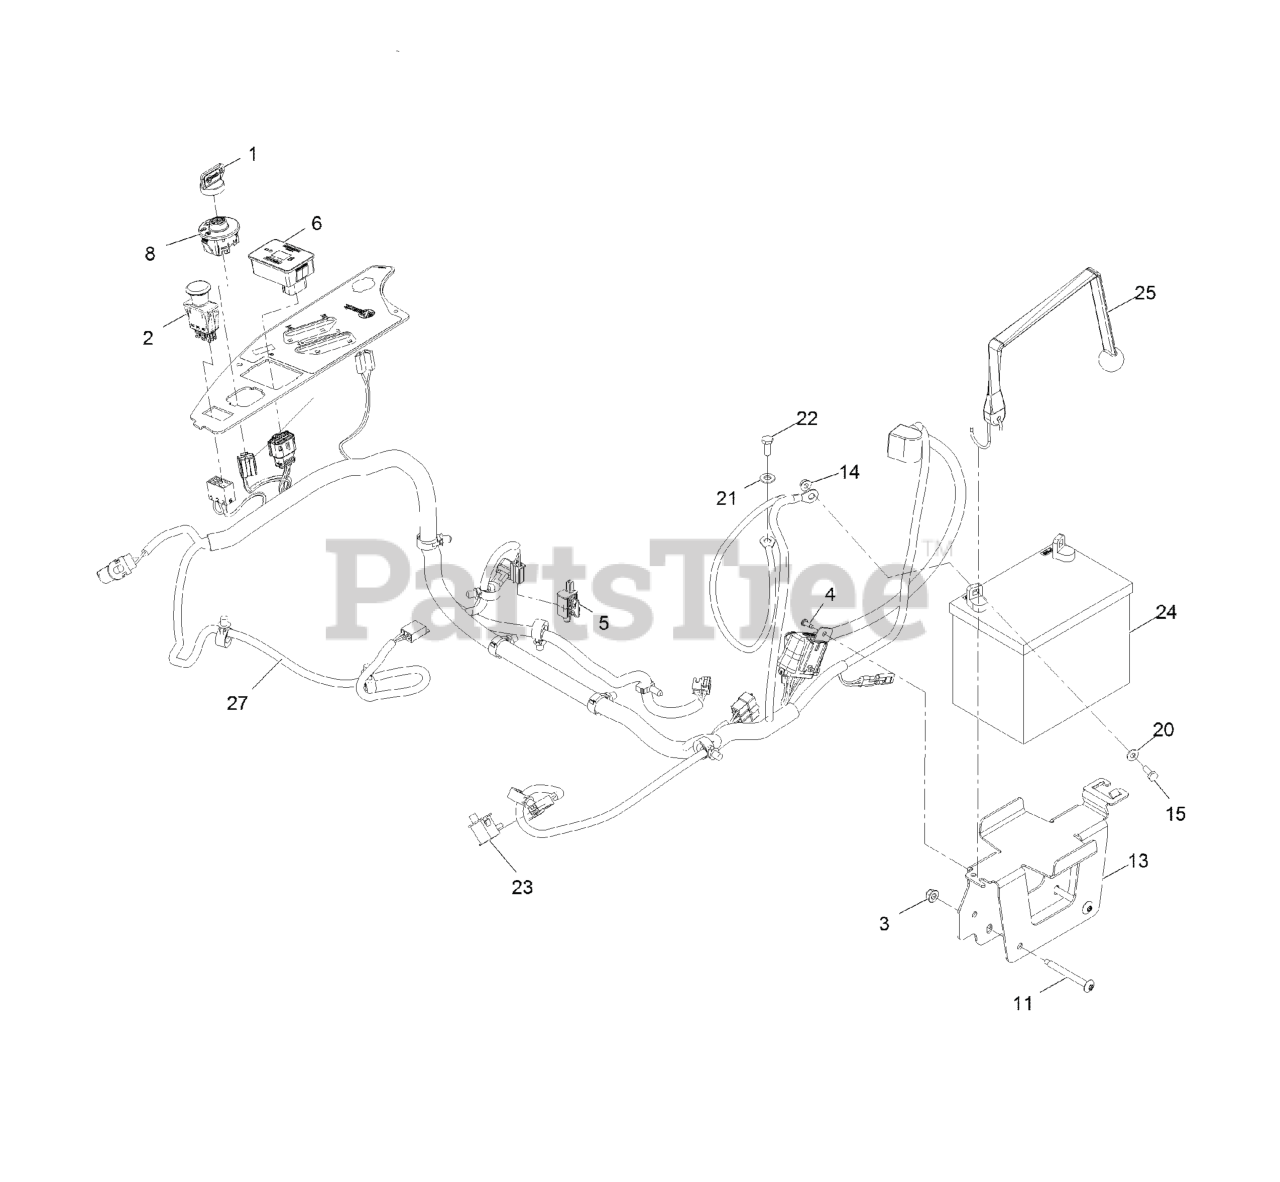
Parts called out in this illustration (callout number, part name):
1	KEYS-IGNITION (SPARE PAIR
1	KEY-IGNITION
2	SWITCH-PTO
3	NUT-HF, NI
4	SCREW-FORMING, THREAD
6	MODULE ASM
8	SWITCH-IGNITION
11	SCREW-TORX
13	TRAY-BATTERY
15	SCREW-HH
20	WASHER-FLAT
21	WASHER-PLAIN
22	SCREW-HH
23	SWITCH-BAIL
24	Battery
25	STRAP-BUNGEE
27	HARNESS - WIRING
